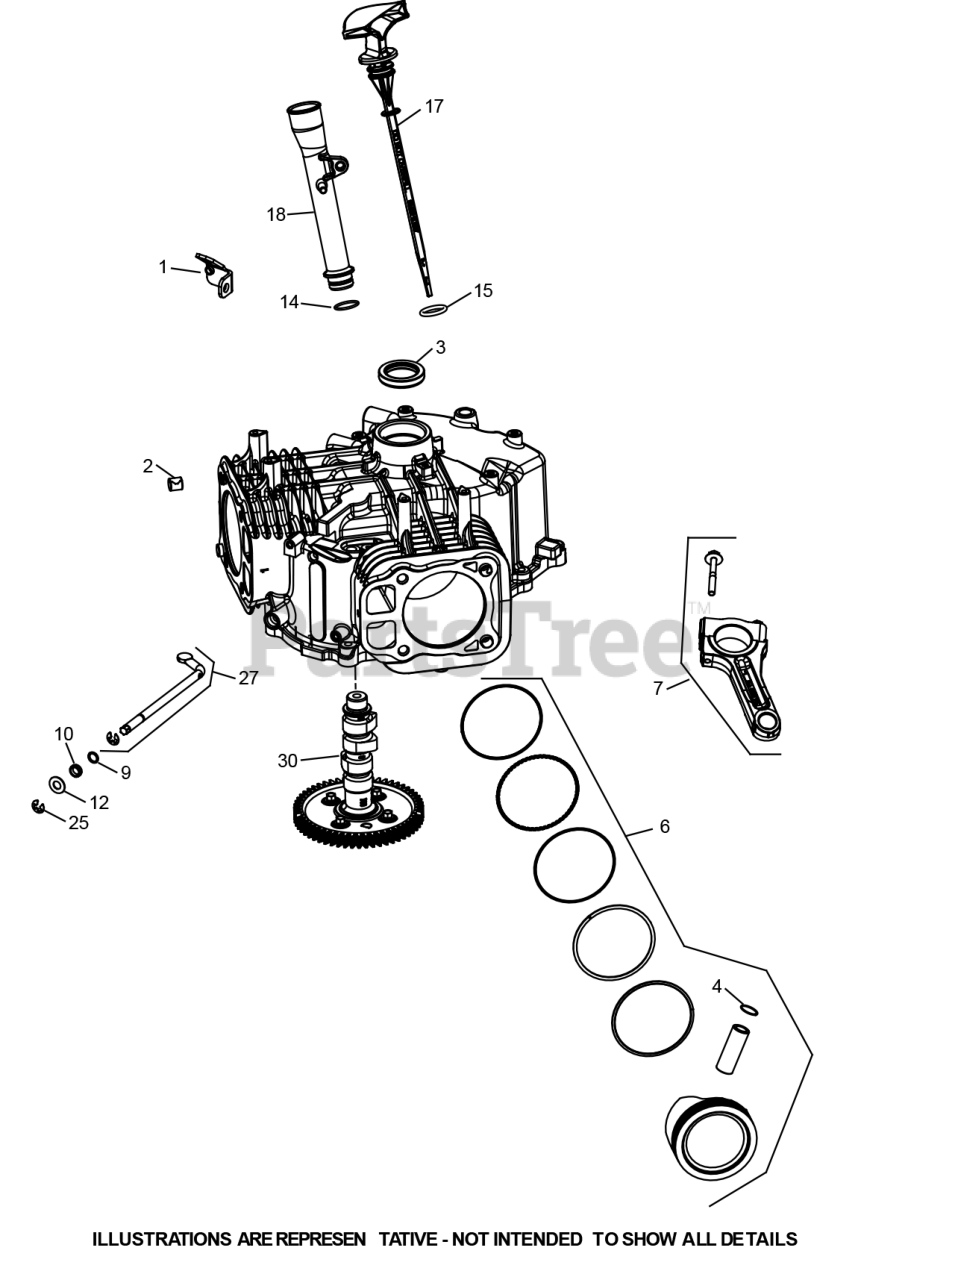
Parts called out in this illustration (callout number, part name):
1	BRACKET-OIL FILL TUBE
2	PIN-SPLIT DOWEL
4	RETAINER-PISTON
6	PISTON KIT (STD)
7	CONNECTING ROD ASSEMBLY
9	WASHER-1/4 FLAT
12	WASHER-9MM FLAT
15	O-RING DIPSTICK
18	DIPSTICK TUBE
25	GOVERNOR SHAFT RETAINER CLIP
27	CROSS CARBURETOR SHAFT KIT
